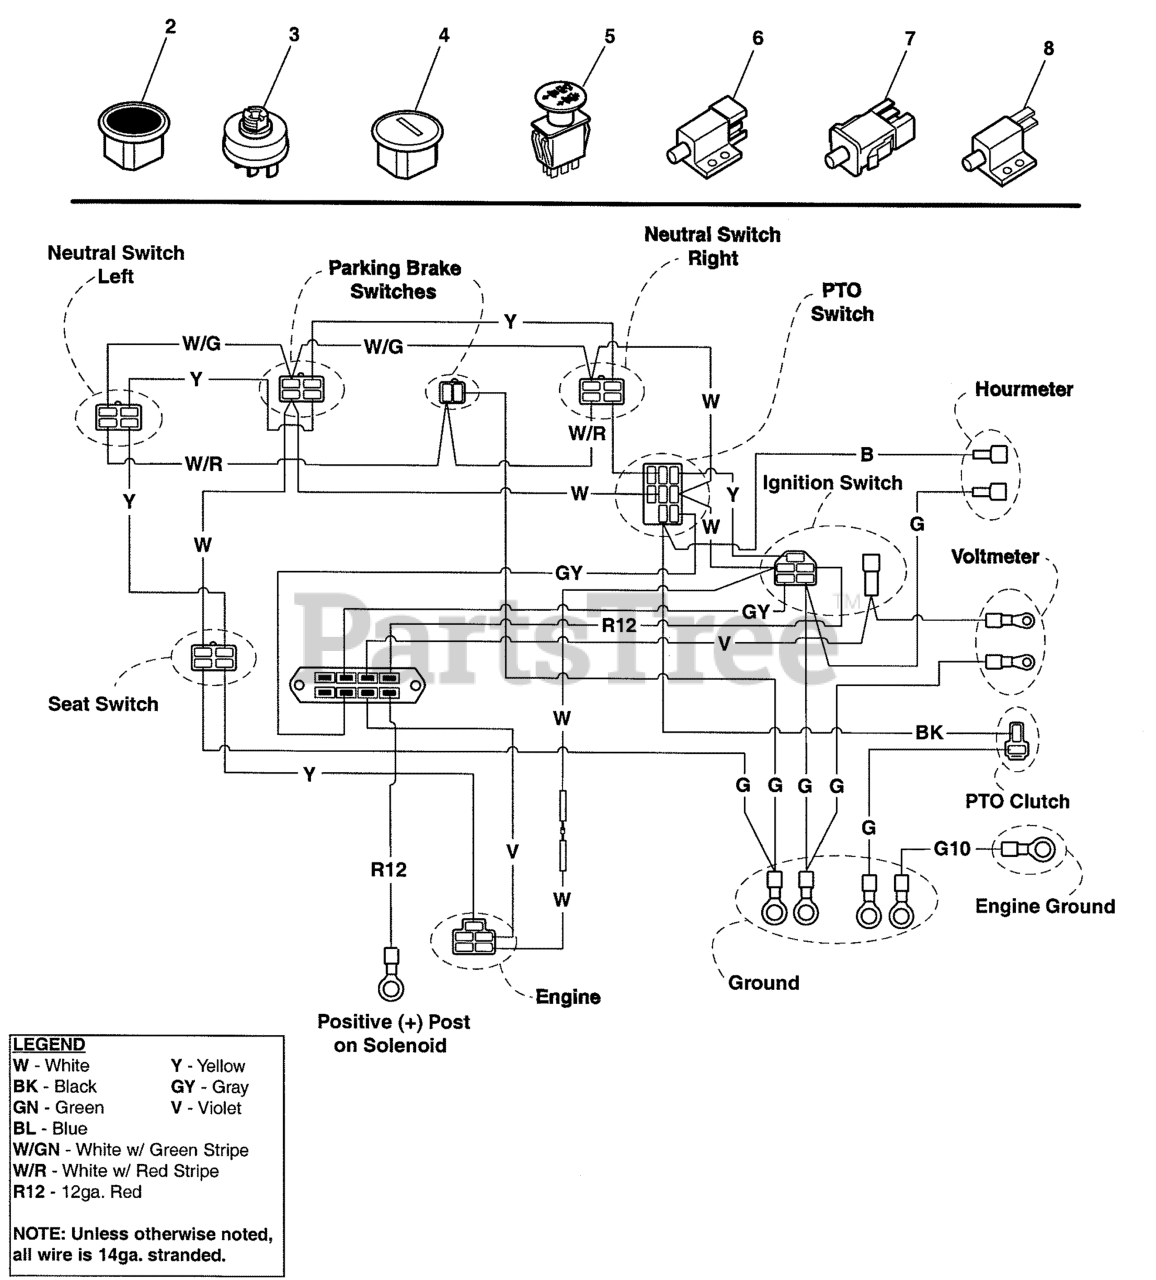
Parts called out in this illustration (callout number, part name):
1	IS4000Z/K25 Wire Harness
2	VOLTMETER
3	SWITCH, IGNITION, 6 POST
4	HOUR METER
5	SWITCH, BLADE ENGAGEMENT
6	SWITCH, PLUNGER, N.O./N.C.
7	SWITCH, DP NO/NC SNAP-IN
8	SWITCH, Plunger, NO
